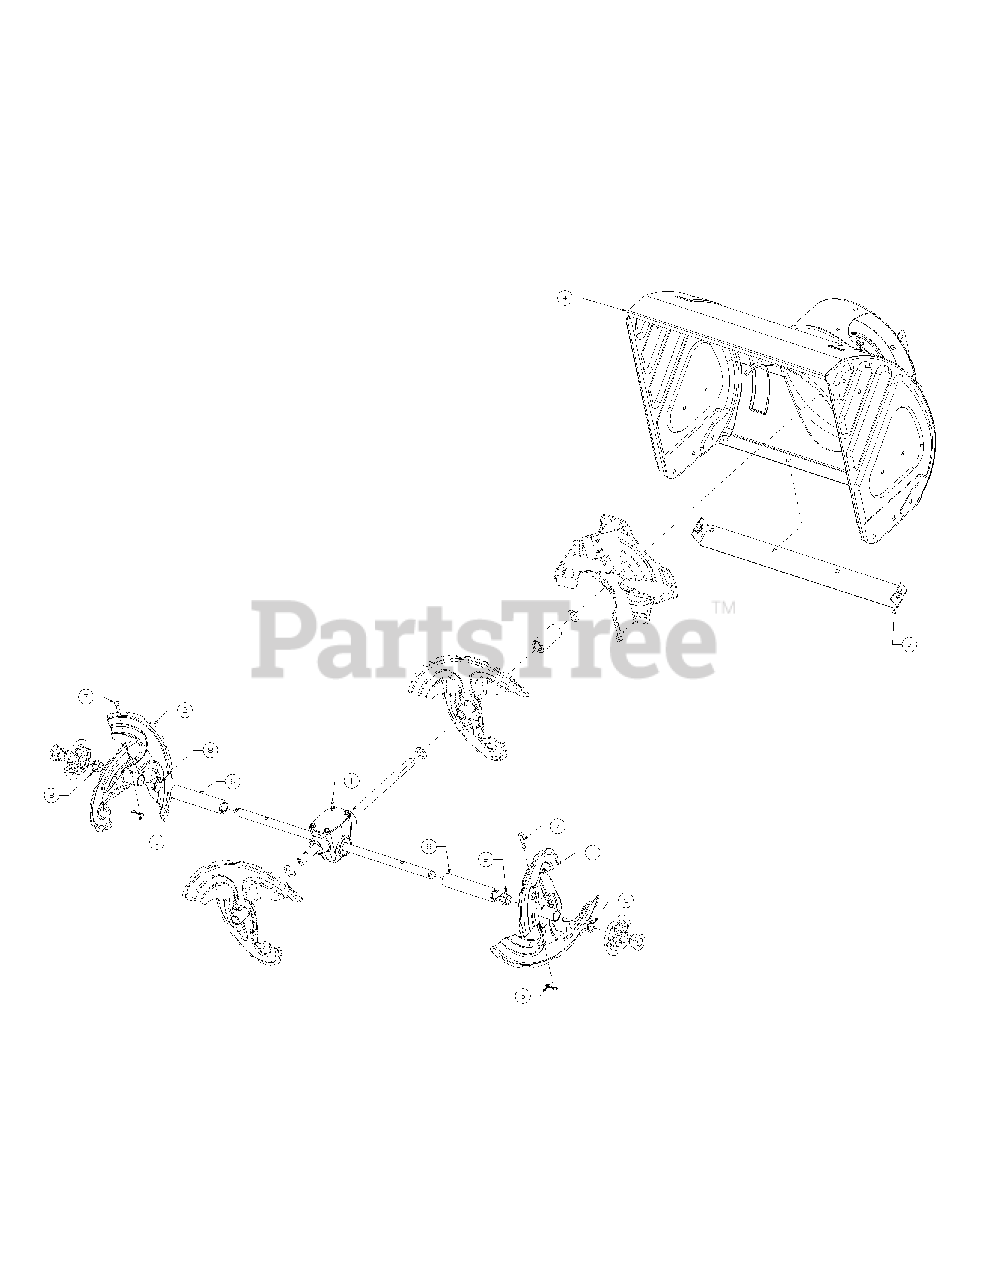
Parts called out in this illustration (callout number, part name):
1	Gearbox Asm-Aug
5	Pin-Cotter
6	Spacer
7	Pin-Shear .25
8	Flange Bearing
